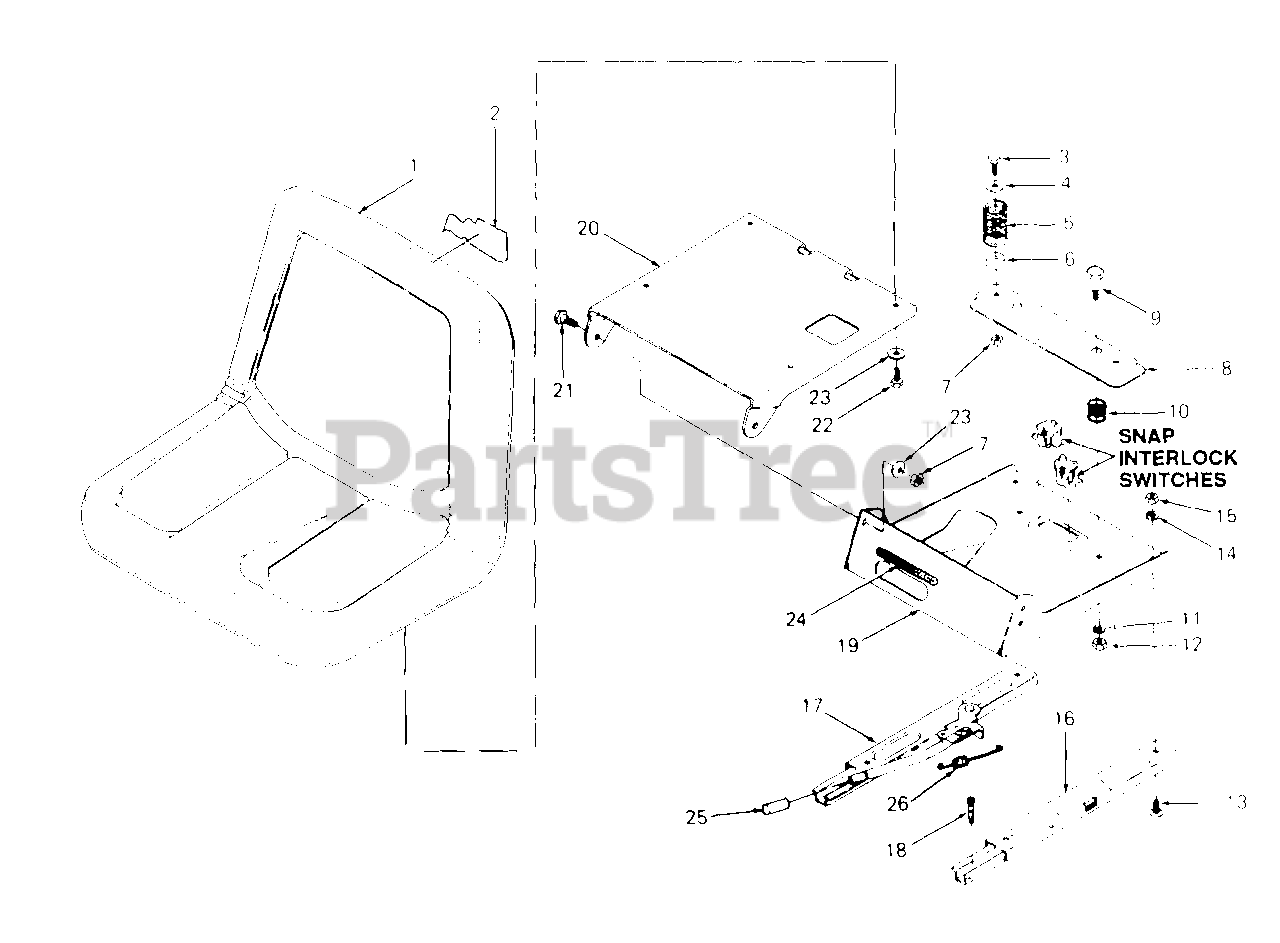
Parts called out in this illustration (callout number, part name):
1	Seat
2	Graphic, Made in USA
3	Screw, Hex Cap, 5/16-18 X .88 Lg GR5
4	Washer, Flat, .344 X .875 X .06 Thk
5	Spring, Comp, 1.28 OD X 2.18 Lg
6	Bushing, .930 OD X .50 Lg
7	Nut, Hex Center Lock, 5/16-18 GR5
10	Spring, Comp, 1.00 OD X .86 Lg
11	Washer, Lock, 3/8
12	Nut, Hex, 3/8-16 GR5
13	Bolt, Sht Nk Carriage, 5/16-18 X .62 Lg
14	Washer, Lock, 5/16
15	Nut, Hex, 5/16-18 GR5
16	Slide, Seat - LH
17	Adjuster, Manual Seat - RH
18	Screw, Socket Hd Cap, 5/16-18 X 1.00 Lg
22	Screw, Hex Cap, 5/16-18 X .75 Lg GR5
23	Washer, Bell, .345 X .88 X .060 Thk
24	Label, Seat Adjustment
25	Cover, Handle
